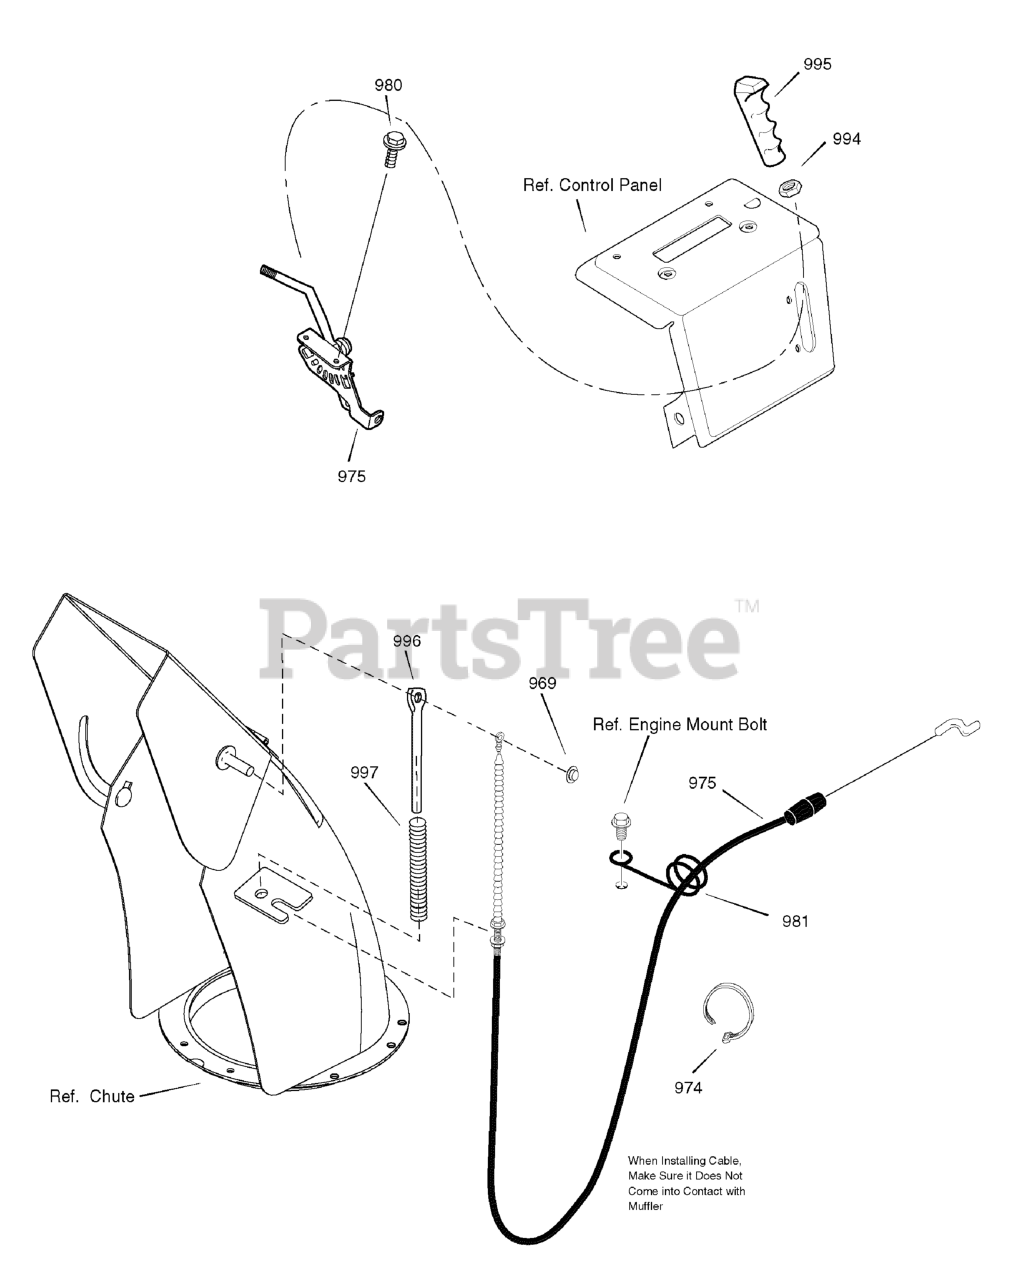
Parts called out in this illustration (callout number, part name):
969	NUT, Push-Cap, 5/16
974	TIE, CABLE
975	LEVER & CABLE, CHUTE DEFLECTOR
980	SCREW
981	WIRE FORM, CHUTE CABLE
994	NUT, 3/8-16
995	KNOB, SHIFT
996	ROD, Spring
997	SPRING, Compression
